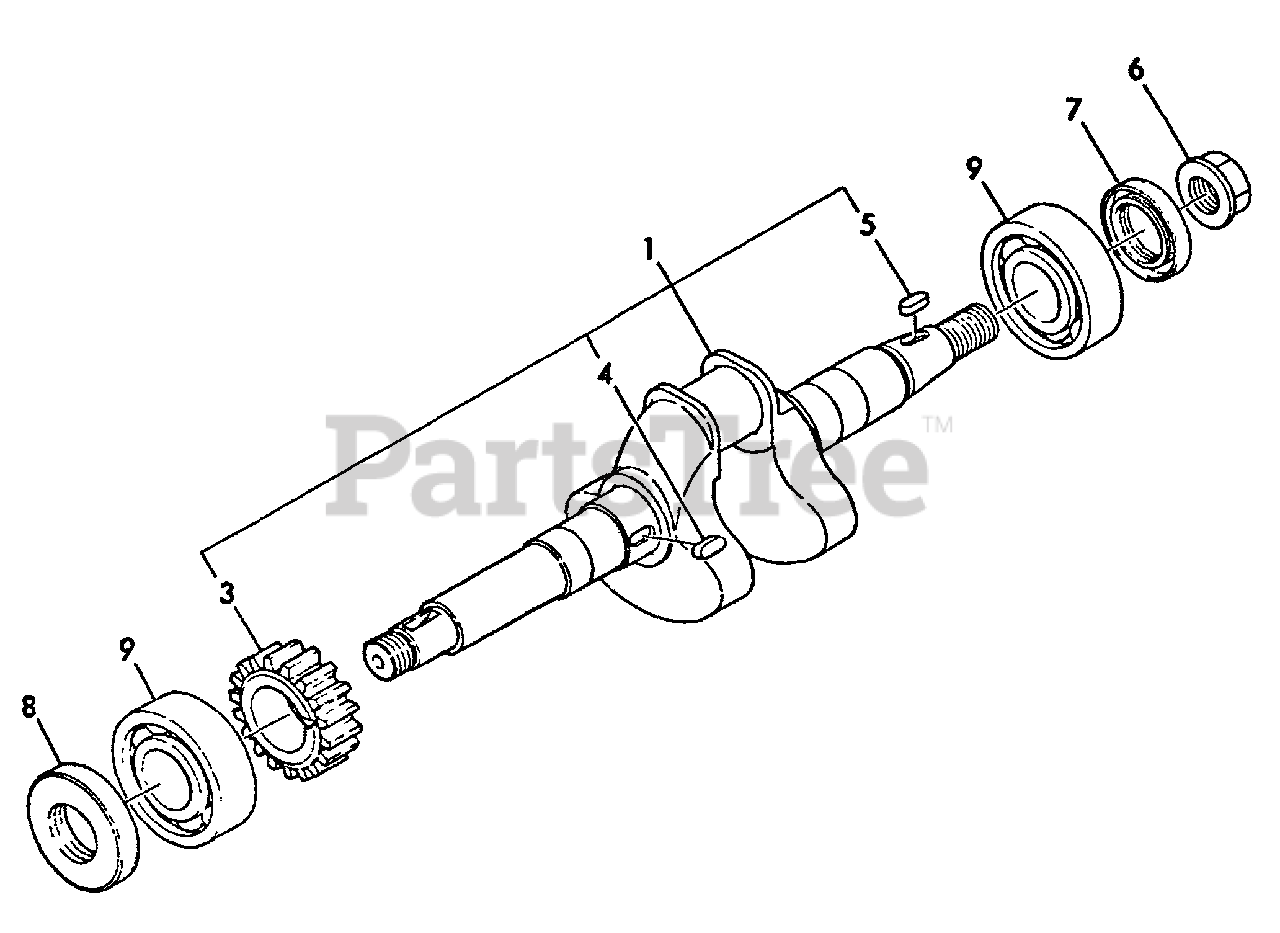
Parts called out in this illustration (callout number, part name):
1	CRANKSHAFT ASSY
3	GEAR, CRANKSHAFT
4	KEY - 4X10
5	KEY - 4X10
6	NUT - 12
7	SEAL, OIL
8	SEAL, OIL
9	BEARING, BALL - 6204C3
